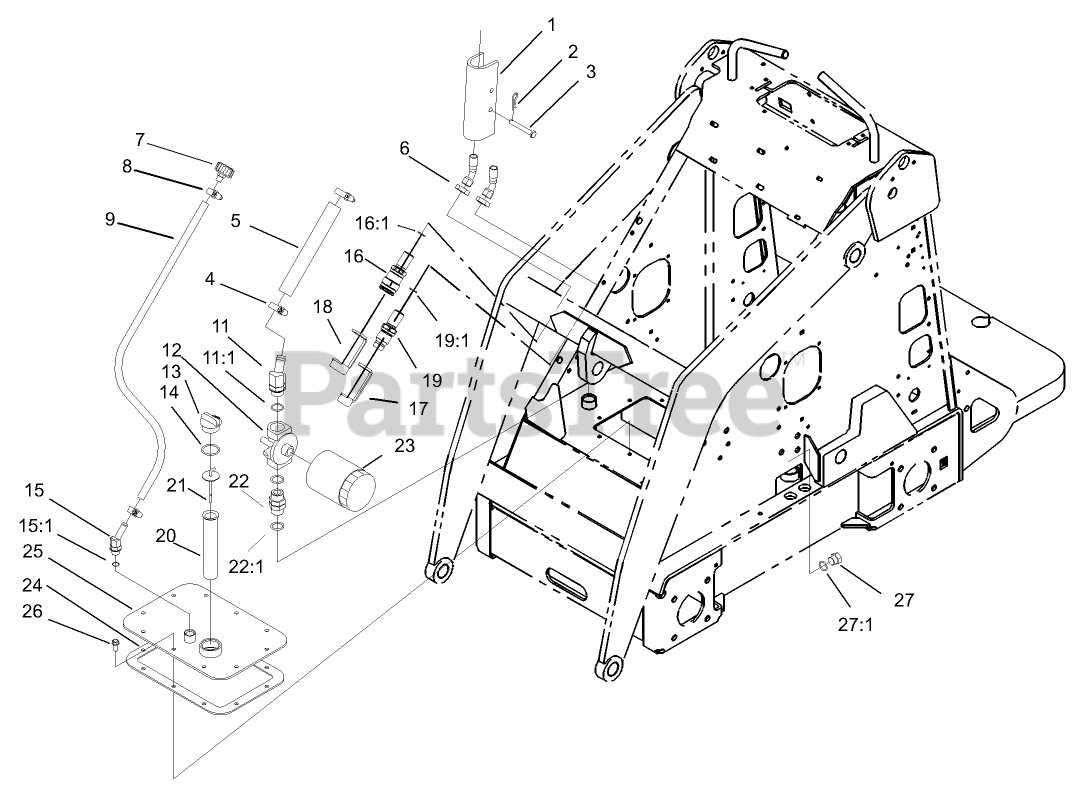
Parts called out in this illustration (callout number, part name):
1	LOCK-CYLINDER
2	PIN-HAIR
3	PIN-CLEVIS
4	CLAMP-HOSE
5	HOSE-SUCTION, HYD
6	NUT-LOCK, BULKHEAD
7	BREATHER
8	CLAMP-HOSE
9	HOSE-VENT
11	ELBOW-45 DEG
11:1	O-RING
12	HEAD-FILTER
13	PLUG-PLASTIC
14	O-RING
15	FITTING-HYD, 45 DEG
15:1	O-RING
16	BULKHEAD COUPLER ASM
16:1	O-RING
17	CAP-DUST, NIPPLE
18	CAP-DUST, COUPLER
19	BULKHEAD NIPPLE ASM
19:1	O-RING
20	FILTER-SCREEN
21	DIPSTICK-OIL
22	FITTING-THREAD, STRAIGHT
22:1	O-RING
23	FILTER-OIL, TRANSMISSION
24	GASKET-COVER
26	SCREW
27	PLUG-HEX
27:1	O-RING
